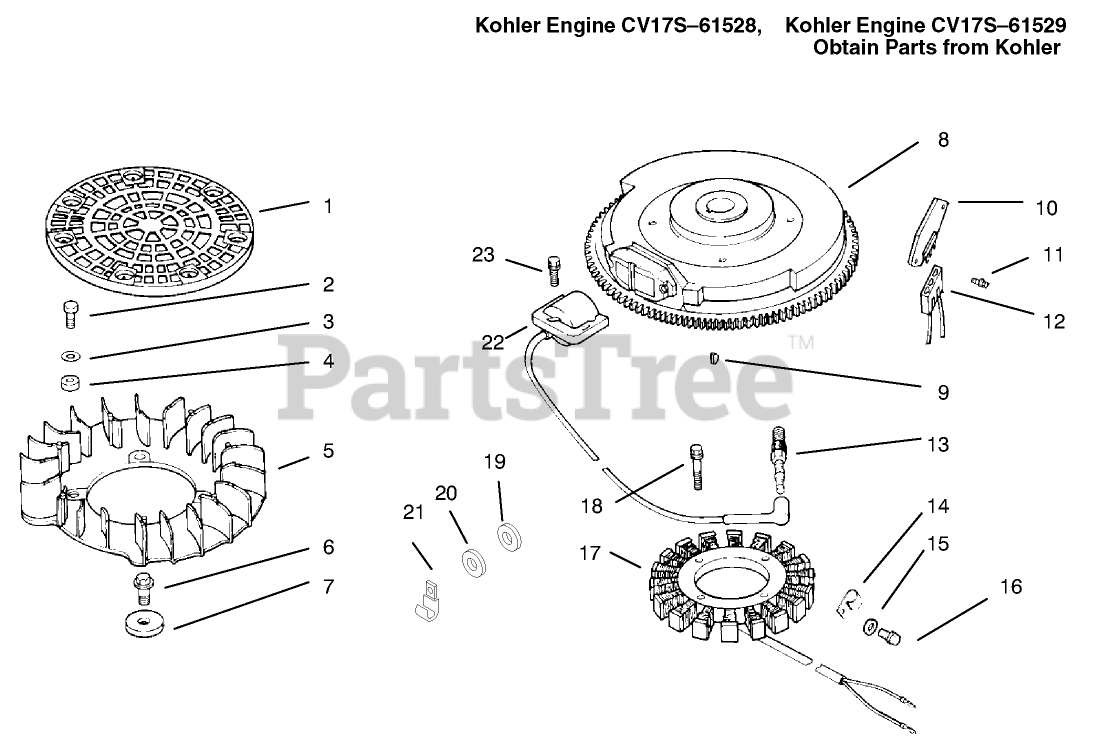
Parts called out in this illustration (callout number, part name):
1	Screen-Grass (Only On: 72103, 72083)
2	Screw-Hex.
3	Washer
4	Spacer-Fan (Only On: 72103)
5	Fan (Only On: 72103, 72083)
7	Spacer-Fan
8	Flywheel ASM (Only On: 72103, 72083)
10	Rectifier-Regulator
12	Connector
13	Spark Plug
16	Screw
17	Stator-15 amp
19	Washer
20	Washer
22	Module-Ignition
